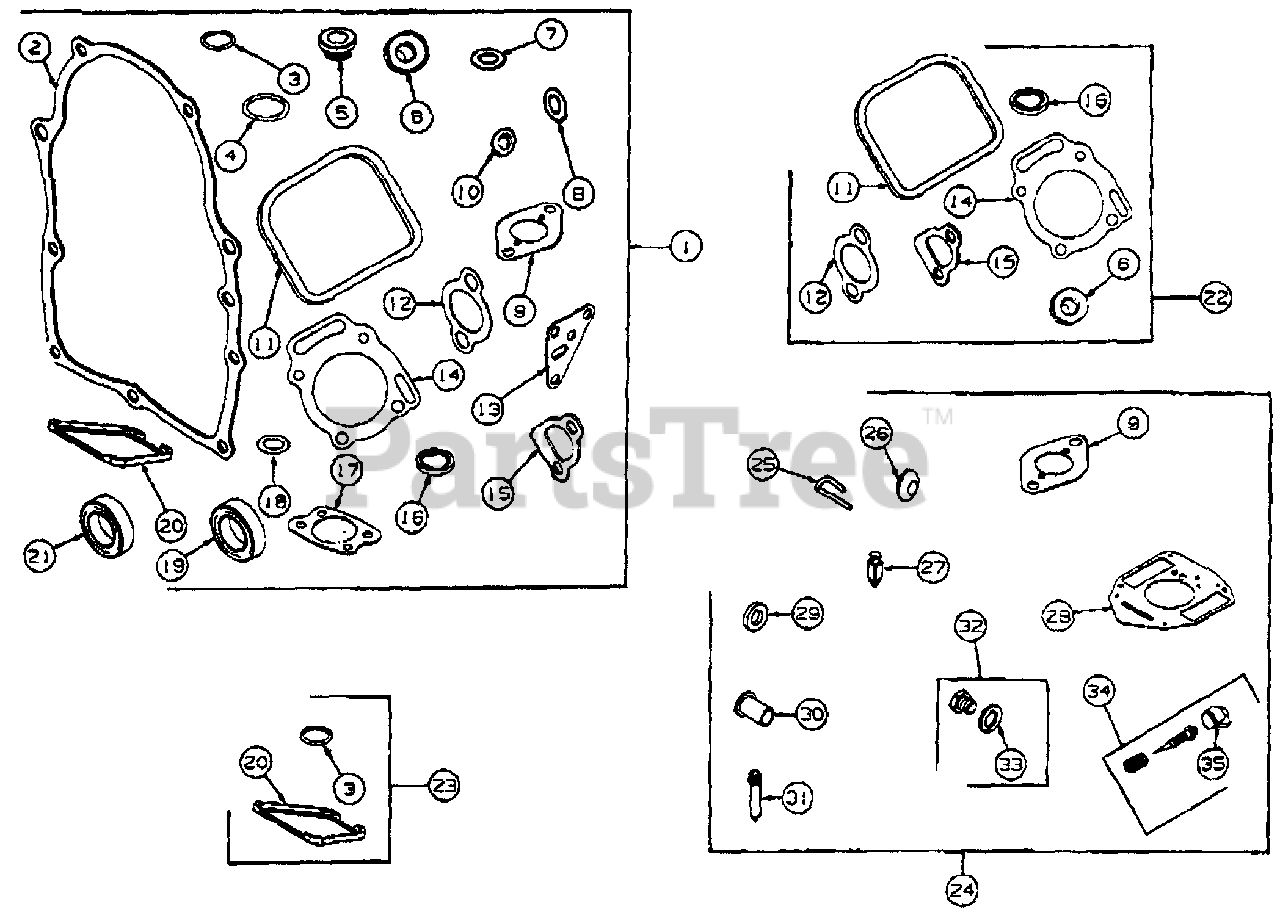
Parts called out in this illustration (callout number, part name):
1	Gasket Set
2	Gasket, Crankcase
3	Seal, Breather Tube
4	Seal, O-Ring
5	Seal, Fill Tube
6	Washer
7	Seal, O-Ring (Crankcase Cover)
8	Seal, O-Ring (Oil Pump)
9	Gasket, Intake
10	Seal, O-Ring (Oil Pump Screen)
11	Gasket, Valve Cover
12	Gasket, Exhaust
13	Gasket, Filter Adapter
14	Gasket, Cylinder Head
15	Gasket, Intake
16	Seal, Fill Plug
17	Gasket, Air Cleaner
18	Seal, Governor Shaft
19	Seal, Oil
20	Gasket, Breather
21	Seal, Oil
22	Gasket Set, Valve
23	Gasket Set, Breather
24	Overhaul Kit, Carburetor
25	Pin, Float Hinge
26	Plug, Welch
27	Valve, Fuel Inlet
28	Gasket, Carburetor Body
29	Collar, Throttle
30	Collar, Choke
31	Nozzle, Carburetor (Slow Speed)
34	Valve, Idle Adjust
35	Cap, Limiter
